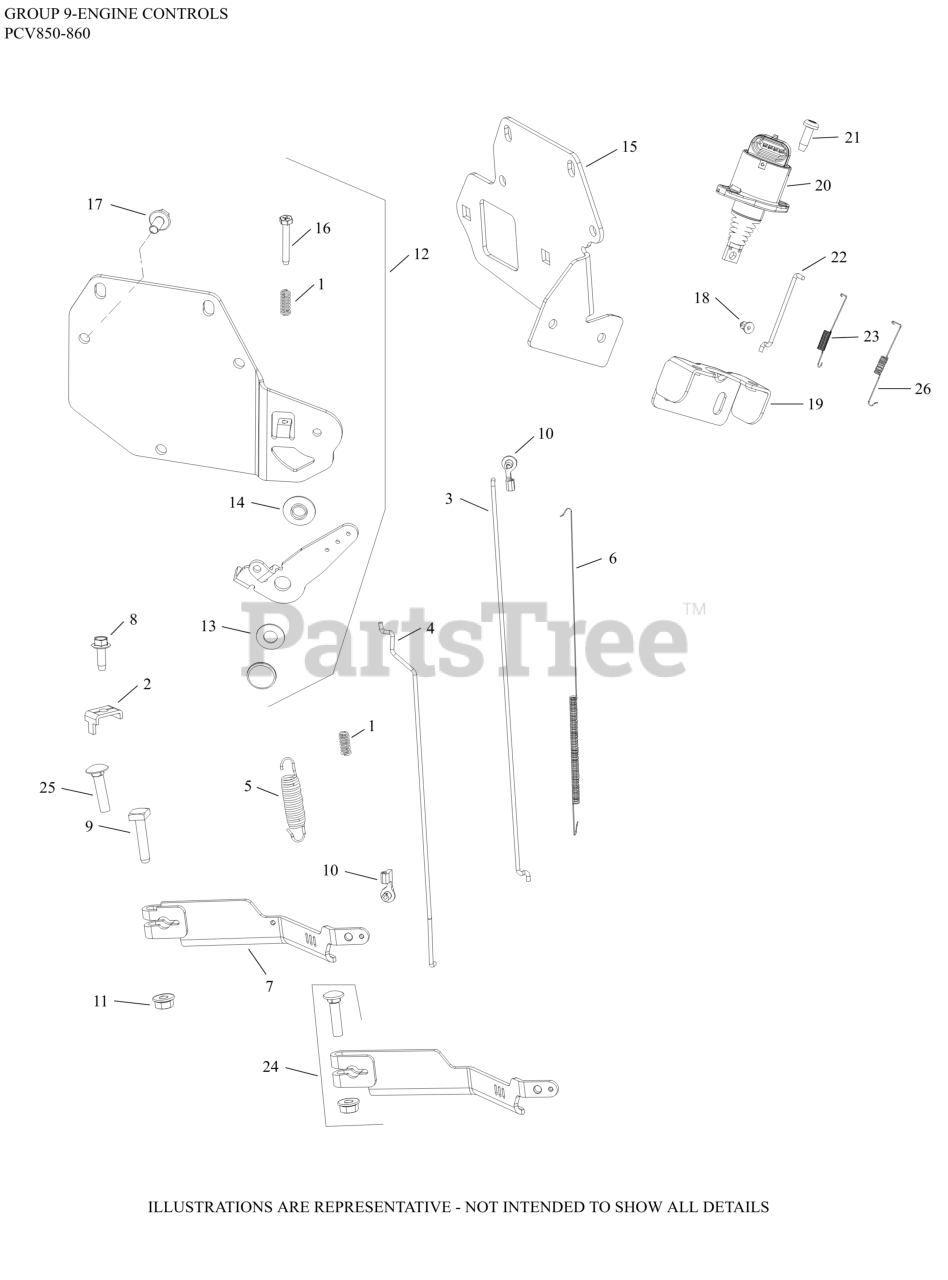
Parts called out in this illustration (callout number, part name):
1	SPRING, SPEED CONTROL (SHORT)
2	CLAMP, CABLE-(#2523753S)
3	LINKAGE, SPEED CONTROL
4	LINKAGE, THROTTLE
5	SPRING, GOVERNOR
6	SPRING, LINKAGE
7	ARM, GOVERNOR-(#1918605S)
8	SCREW, THREAD FORMING
9	SCREW, T HEAD
10	BUSHING, THROTTLE LINKAGE
11	NUT, HEX FLANGE
12	BRACKET, ASSEMBLY THROTTLE CONTROL
14	WASHER, NYLON SHOULDER
16	KIT, IDLE ADJ SCREW & SPRING
